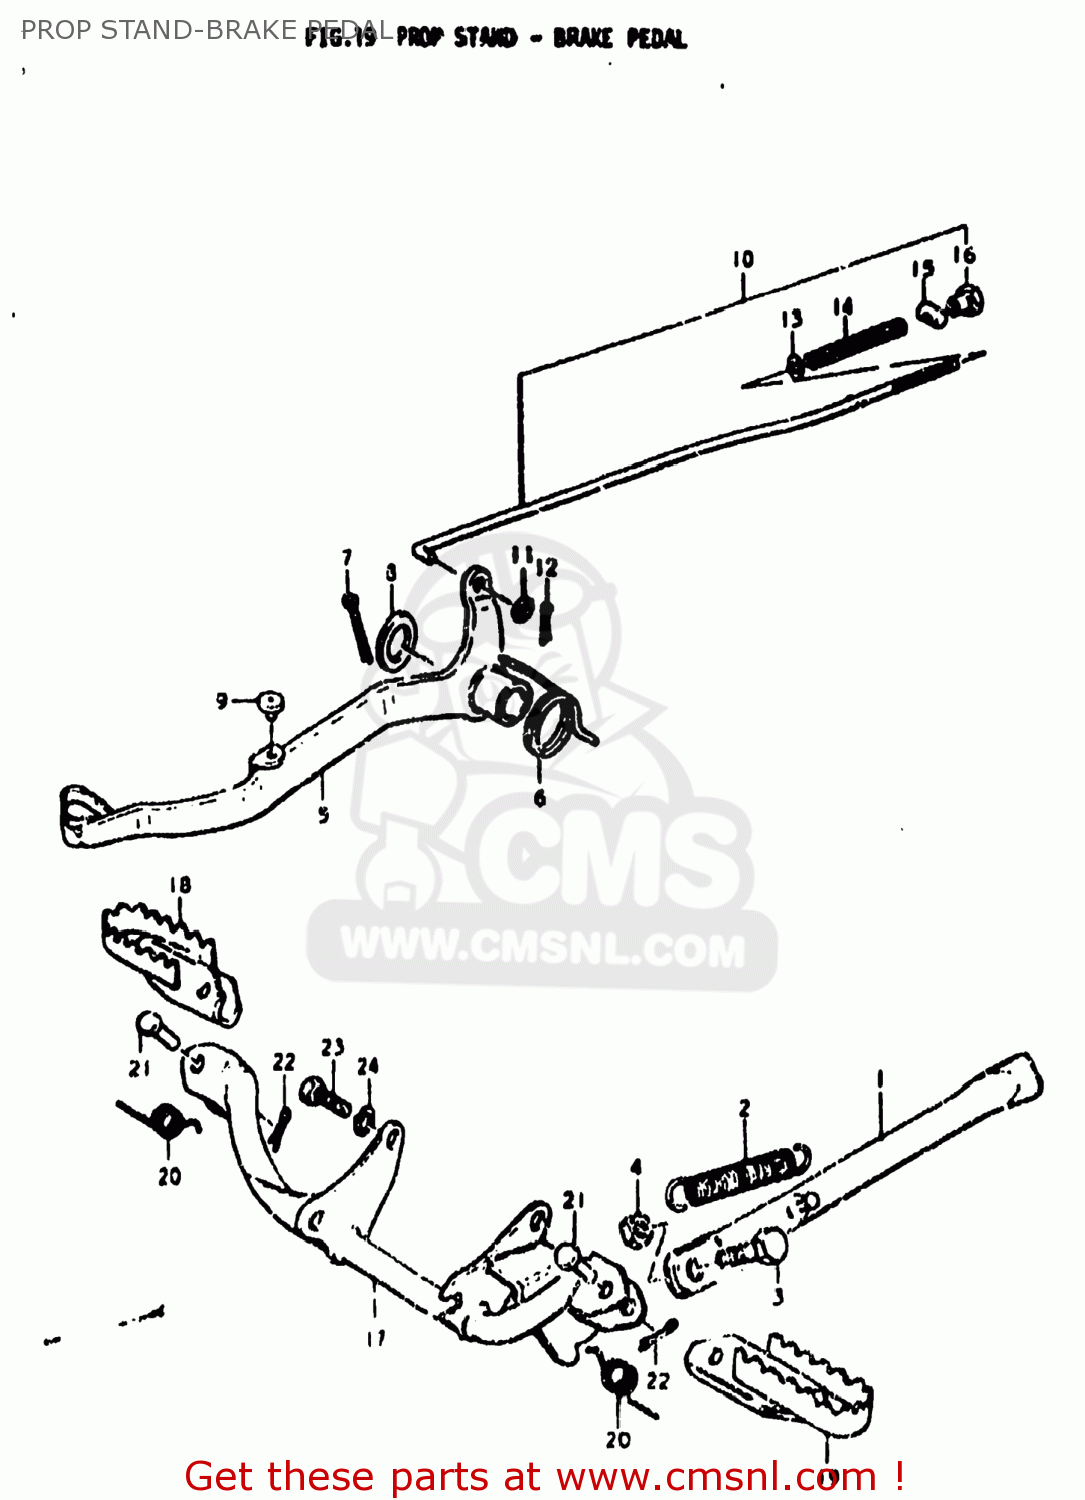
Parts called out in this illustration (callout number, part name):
1	STAND,SIDE
2	SPRING
3	BOLT
4	NUT
5	PEDAL,BRAKE
6	SPRING
7	COTTER PIN
8	WASHER(15.5X26X2.3)
9	STOPPER,BRAKE PEDAL
10	ROD ASSEMBLY,REAR BRAKE
11	WASHER
12	PIN 20X20
13	WASHER
14	SPRING
15	PIN(11X18)
16	NUT
17	BAR,FRONT FOOTREST
18	FOOTREST,FRONT,RIGHT
19	FOOTREST
20	SPRING
21	PIN
22	PIN 20X20
23	BOLT
24	LOCK WASHER
